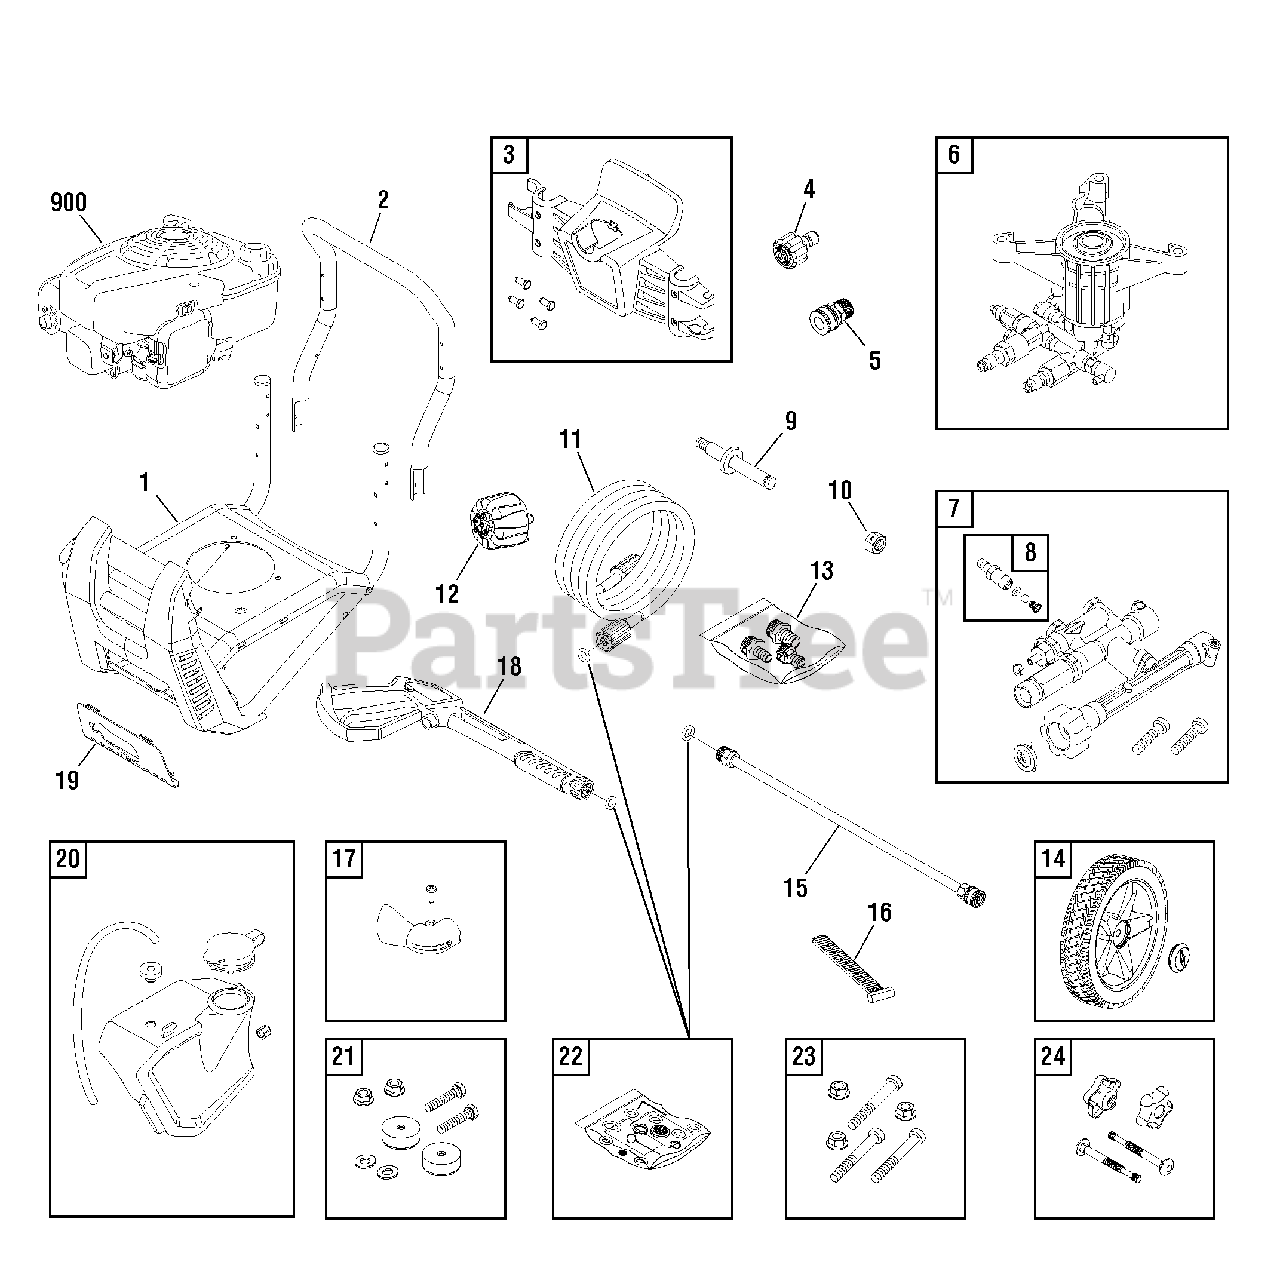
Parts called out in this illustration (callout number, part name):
4	QUICK CONNECT
5	QUICK CONNECT
6	PUMP
13	KIT-GARDEN HOSE
17	DEFLECTOR-EXHAUST
20	TANK-CHEMICAL
21	MOUNT-VIBRATION
23	KIT-HARDWARE PUMP MOUNTING
24	KIT-HARDWARE HANDLE
900	* ENGINE
